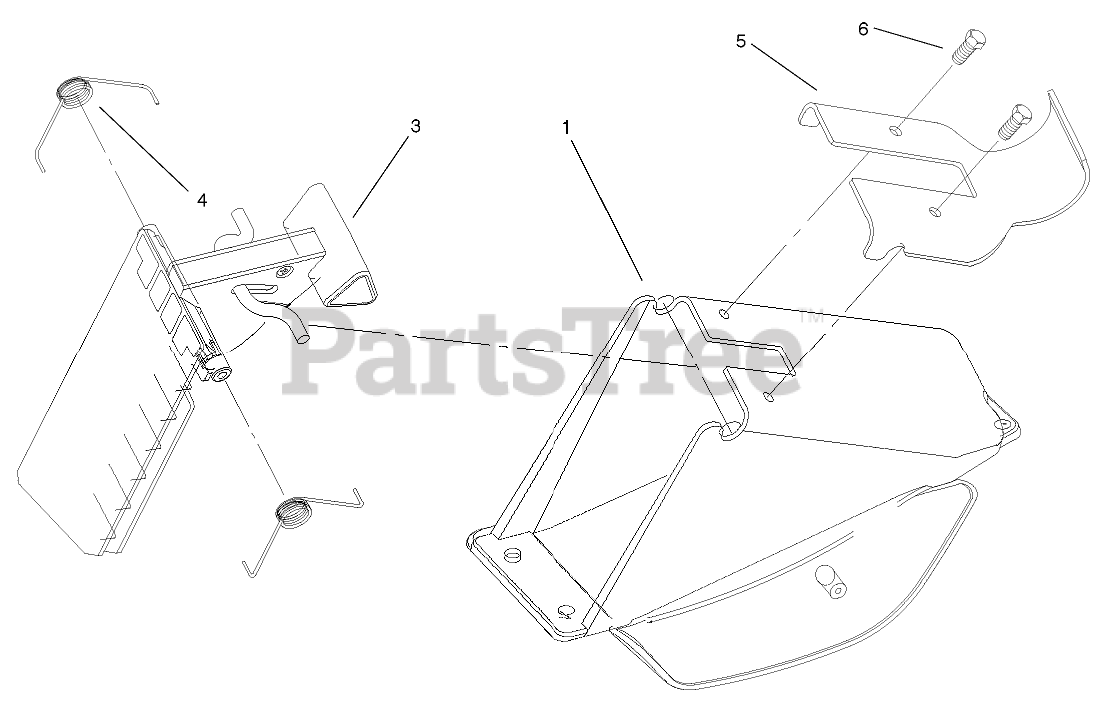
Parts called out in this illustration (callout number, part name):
1	CHUTE - DISCHARGE
3	ASM - DISCHARGE DOOR
4	SPRING-DOOR, RH
5	Plate-Discharge Chute
6	SCREW-PLASTITE
